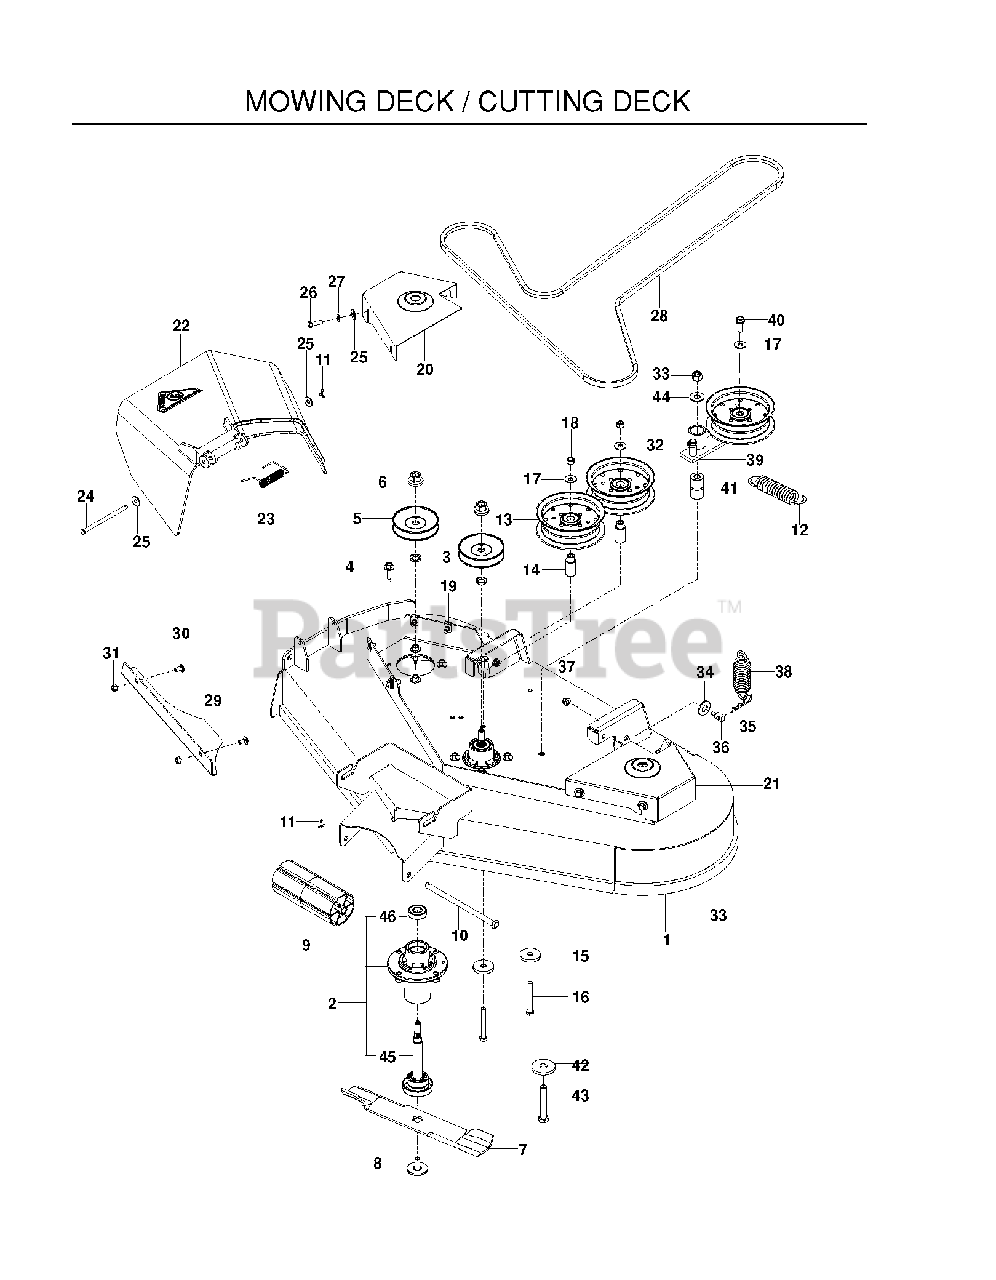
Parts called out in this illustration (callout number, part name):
1	DECK SVC W/DECALS 42 RZ ORANGE
2	MANDREL.DECK.ASSEMBLY
3	WASHER-SPACER
4	WASHER HEAD SCREW
5	PULLEY, MADREL 3.70 OP
6	LOCKNUT - 9/16
7	BLADE, 14 5/8"
8	BLADE BOLT ASSY-7/16" TB REPL
9	NOSE ROLLER 48"
10	NOSE ROLLER ROD
11	RP_COTTER PIN 1/8 X 3/4
13	PULLEY, IDLER
14	IDLER BUSHING
15	SPINDLE WASHER
16	HCS 3/8C X 3
17	RP WASHER 3/8 FLAT
18	NUT 3/8-16 NYLOC
19	U-CLIP 5/16-18 NUT RETAINER
20	BELT SHIELD, RIGHT 42, ORG
21	BELT SHIELD, LEFT 42, ORG
22	DISCHARGE CHUTE 42"
23	SPRING - TORSION
24	PIN-CLEVIS 5/16 DIA X 5.19 ZD
25	WASHER 5/16 FLAT
26	HCS 5/16C X 1
27	WASHER 5/16 LOCK
29	CONFINEMENT.PLATE.42".BLACK
30	CARRIAGE BOLT 5/16C X 5/8"
31	NUT 5/16 NYLOC
32	ZERK
33	RP NUT 1/2-13 HEX NYLOC ZD
34	WASHER 5/8 FLAT
35	HAIRPIN #4
36	STUD.FASTNER.W/ANTI-ROTATE
37	5/16-18 NYLOC FLANGE NUT
40	4CS 3/8C X 1 SERRATED HEAD
41	PIVOT BUSHING
42	WASHER, SUPPORT
43	HCS 1/2C X 3 1/4
44	WASHER 1/2 FLAT
45	STUD.FASTNER.W/ANTI-ROTATE
46	BEARING, BALL
